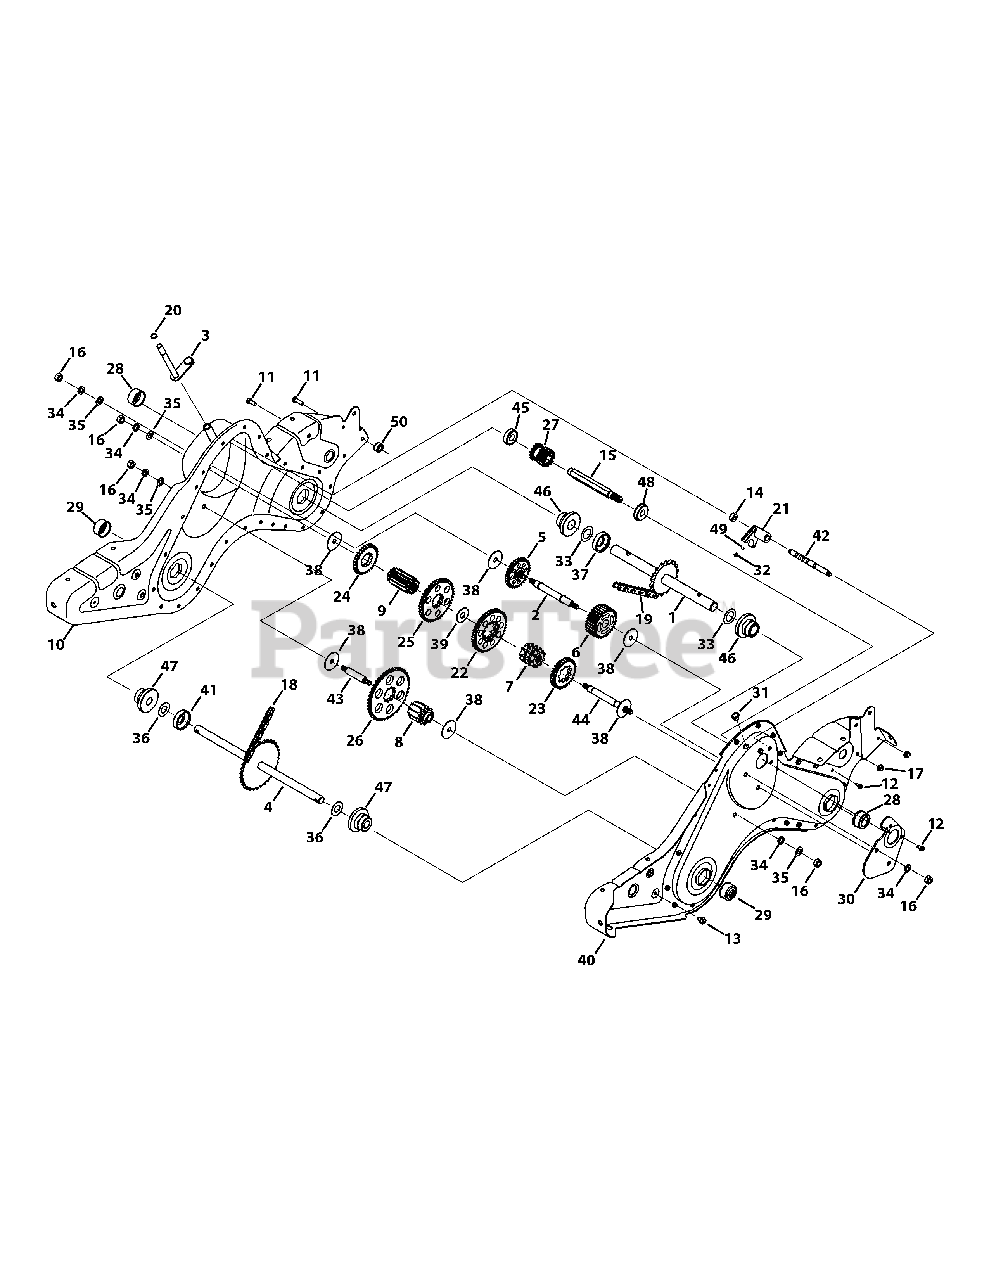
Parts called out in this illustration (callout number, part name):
1	Shaft Assembly, Tine, 18T
2	Shaft Assembly, Jack
3	Shaft Assembly, Shift Input
4	Shaft Assembly, Wheel, 33T
5	Gear Assembly, 30T Reverse Idler
6	Gear Assembly, 30T Tine Idler
7	Sprocket Assembly, 9T Tine Input
8	Sprocket Assembly, 10T Whl Input
9	Gear Assembly, 11T
10	RH Chain Case Housing Assembly
11	Hex Head Screw, 5/16-18 x 100
12	Screw, 1/4-20 x 0625
13	Screw, :5/16-18 x 075
14	Spacer, 505 ID x 88 OD x 440
15	Input Shaft, 75
16	Nut, Hex, 7/16-20
17	Nut, Flangelock, 5/16-18
18	Endless Chain, #420 x 50 Links
19	Endless Chain, #50 x 54 Links
20	Snap Ring, 500
21	Clutch Collar
22	Gear Spur, 44T
23	Gear Spur, 30T
24	Gear Spur, 30T
25	Gear Spur, 44T
26	Gear Spur, 44T
27	Gear Spur, 16T
28	Shaft Seal, 10
29	Shaft Seal, 75
30	Positioner Gear Bracket
31	Tapered Cap Plug
32	Compression Spring, 230 OD
33	Washer, Flat, 103 x 162 x 03
34	Washer, Lock, 7/16
35	Washer, Flat,474 x 879 x 064
36	Washer, Flat, 760 ID x 150 OD
37	Spacer, 10 ID x 20 OD x5 LG
38	Washer, Thrust, 445 x 192 x 040
39	Washer, Flat,1595 x 635 x 062
40	LH Chain Case Housing
41	Spacer, 75 x 20 x 50
42	Shaft Detent, 5 DIA
43	Shaft, Jack, 625 x 2385
44	Shaft, Jack, 6250 x 50050
45	Ball Bearing, 17 x 40 x 12:6203
46	Flange Bearing, 10 x 25 x 138
47	Flange Bearing, 75 x 25 x 138
48	Ball Bearing, 17 x 40 x 12:6203
49	Ball, Detent, 250
50	Spacer, 315 x 750 x 375 LG
